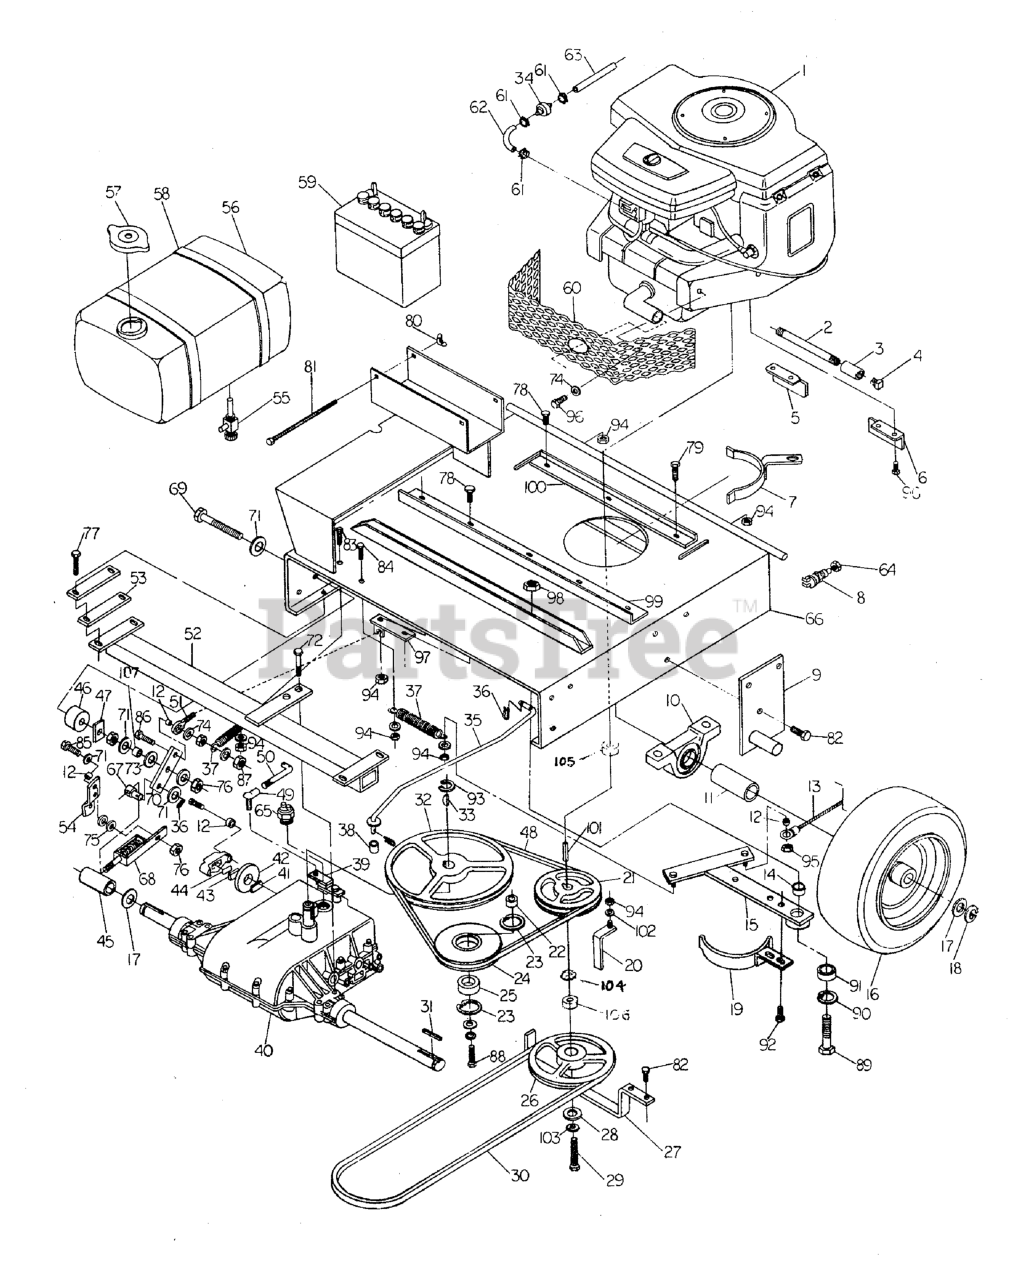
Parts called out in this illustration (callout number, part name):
1	ENGINE, 18HP Briggs & Stratton
2	Oil Drain Extension
3	Coupler
4	Pipe Plug
5	Heat Shield Right
6	Heat Shield Left
7	ENGINE BELT GUIDE
8	Safety Switch
9	Pivot Bracket - LH
10	Pillow Block Bearing
11	SPACER, .76 x 1.00 x 3.38
12	Cable Spacer
13	Clutch Cable
14	BUSHING, Brass
15	Transmission Bell Crank Weld
16	Drive Tire Assembly (Tire & Rim)
16	Tire Only
16	Rim Only
16	DRIVE HUB
17	SHIM
18	C-CLIP
19	Idler Pulley Belt Guide
20	Belt Guide
21	ENGINE PULLEY
22	INSERT, Bearing
23	SNAP RING, Internal
24	Idler Pulley Clutch
25	BEARING, BALL 11/16X1-9/16X15/32
26	ENGINE PULLEY
27	Belt Guide
28	SPACER, .63 x 1.00 x .63
29	BOLT, 7-16-20 x 1-1/2
30	BELT, B Section
31	KEY, 3/16" SQ. X 2-1/2
32	Transaxle Pulley
33	Hy Pro Key
34	FUEL FILTER
35	Brake Linkage Adjustment Rod
36	HAIRPIN CLIP
37	SPRING, Extension
38	SLEEVE
39	Shifting Lever
40	Transaxle
41	Brake Pad
42	Brake Disc
43	Brake Pad
44	Brake Pad Plate
45	SPACER, .76 x 1.00 x 1.88
46	Nylon Roller
47	Brake Mount
48	Belt A Section
49	BALL JOINT, 3/8" Female Studded
50	Shifting Linkage
51	Brake Cable
52	Transaxle Support Weldment
53	Transaxle Support Spacer
55	Needle Valve
56	Fuel Tank, 4 Gallon
57	Gas Cap
58	Gas Tank Strap
59	BATTERY, 11U1L, 350 CCA
60	Muffler Guard
61	CLAMP, Hose
62	Fuel Hose Short
63	Fuel Hose Long
64	Brass Nut
65	Neutral Safety Switch
66	Engine Deck Weldment
67	Brake Linkage Adjuster
68	Brake Overload Assembly
69	3/8-16 x 3-1/2 GD 5 Tap Bolt
70	Brake Lever
71	3/8 Flat Washer
72	5/16-18 x 2-3/4 GD 5 Bolt
73	3/8 Flat Washer
74	1/4 Flat Washer
75	1/2 Flat Washer
76	3/8-16 Lock Nut
77	5/16-18 x 1-1/2 GD 5 Bolt
78	5/8-18 x 1 GD 5 Hex Head Cap Screw
79	5/16-18 x 2 GD 5 Bolt
80	5/16-18 Wing Nut
81	5/16-18 x 6 Carriage Bolt
82	5/8-18 x 1 Bolt
83	5/16-18 x 1-1/4 GD 5 Tap Bolt
84	5/16-18 x 1-3/4 GD 5 Tap Bolt
85	3/8-16 x 1-1/4 GD 5 Bolt
86	1/4-20 x 2-1/4 GD 5 Bolt
87	1/4 Lock Nut
88	3/8-16 x 1-3/4 GD 5 Bolt
89	1/2-20 x 2-1/4 GD 5 Bolt
90	SNAP RING, Internal
91	BEARING, BALL 11/16X1-9/16X15/32
92	5/16-18 x 5/8 GD 5 Bolt
93	RING, External, Snap
94	5/16-18 Serrated Flange Nut
95	1/4-20 Lock Nut
96	1/4-29-1/2 GD 5 Hex Head Cap Screw
97	Brake Cable Mount Weldment
98	1/2-20 Lock Nut
99	Front Engine Deck Support
100	Rear Engine Deck Support B & S
101	KEY, 1/4 SQ. X 3
102	5/16 Lock Washer
103	7/16 Lock Washer
104	1/8" Spacer
105	Engine Spacer
106	Engine Shaft Extension
